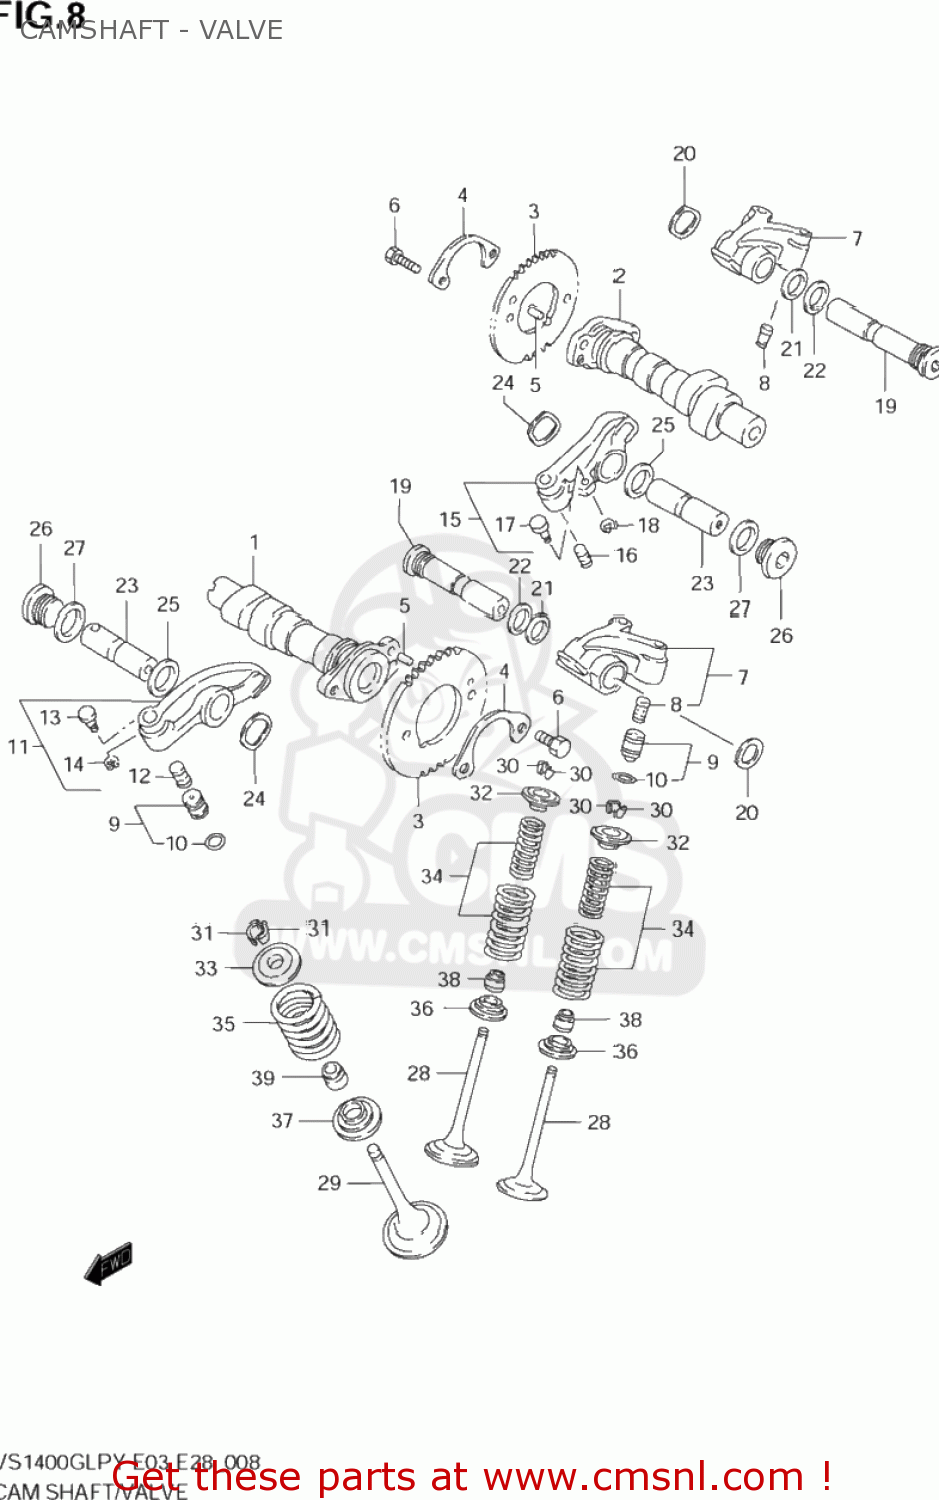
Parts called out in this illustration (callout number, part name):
1	CAMSHAFT,FR
2	CAMSHAFT,RR
3	SPROCKET,CAMSHAFT
4	WASHER,CAM CHAIN SPROCKET
5	PIN
6	BOLT(6X12.5)
7	ARM,VALVE ROCKER INTAKE
8	CHAMBER,VALVE LASH ADJUSTER
9	ADJUSTER,HYDRAULIC VALVE
10	O-RING,ADJUSTER
11	ARM,VALVE ROCKER FR EXHAUST
12	CHAMBER,VALVE LASH ADJUSTER
13	PIN,DECOMP
14	E RING
15	ARM,VALVE ROCKER RR EXHAUST
16	CHAMBER,VALVE LASH ADJUSTER
17	PIN,DECOMP
18	E RING
19	SHAFT,INTAKE VALVE ROCKER ARM
20	WASHER
21	WASHER
22	GASKET(16X22X2) (NAS)
23	SHAFT,EXHAUST VALVE ROCKER ARM
24	WASHER
25	WASHER(16X26X1)
26	PLUG,18X11
27	GASKET(18X24.2X2) (NAS)
28	VALVE,INTAKE
29	VALVE,EXHAUST
30	COTTER,VALVE
31	COTTER,VALVE
32	RETAINER,VALVE SPRING
33	RETAINER,VALVE SPRING
34	SPRING SET,VALVE
35	SPRING,VALVE OUTER
36	SEAT,VALVE SPRING
37	SEAT,VALVE SPRING
38	SEAL,OIL(5.5X11X8.2)
39	SEAL,OIL(7X14.4X9)
